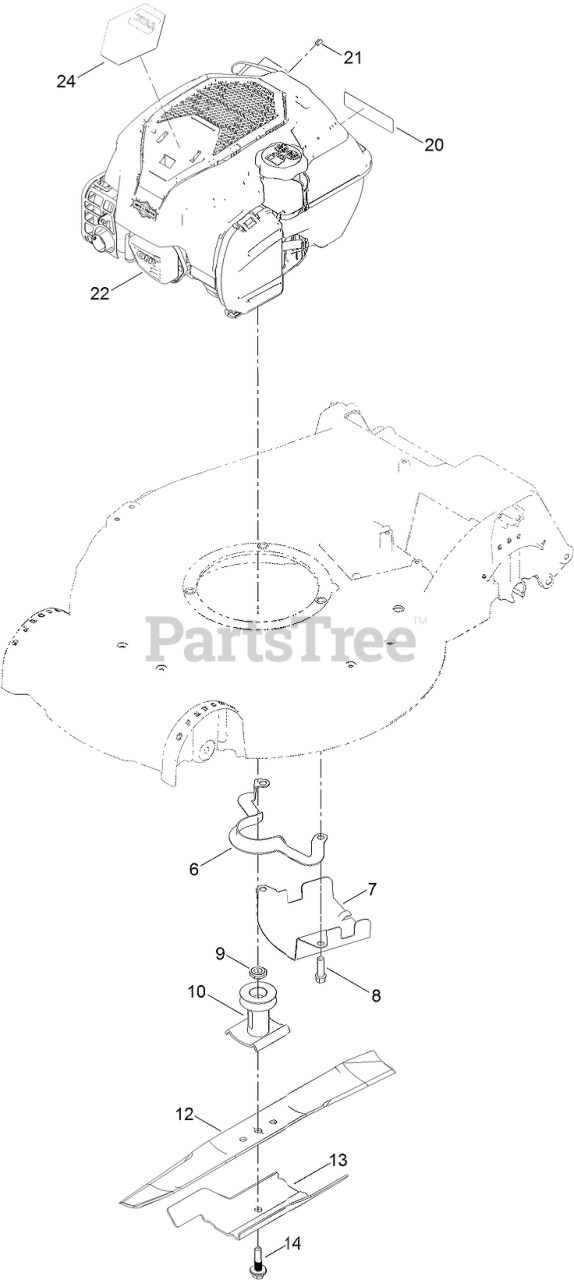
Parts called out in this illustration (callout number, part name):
6	GUIDE-BELT
7	SHIELD-GRASS
8	SCREW-TAPTITE
9	SPACER-DRIVER
10	DRIVER-BLADE
12	BLADE-21IN, RECYCLING
13	ACCELERATOR-BLADE
14	BOLT-BLADE
20	DECAL-ARRESTOR, SPARK
21	STOP-ROPE
24	DECAL-ENGINE
